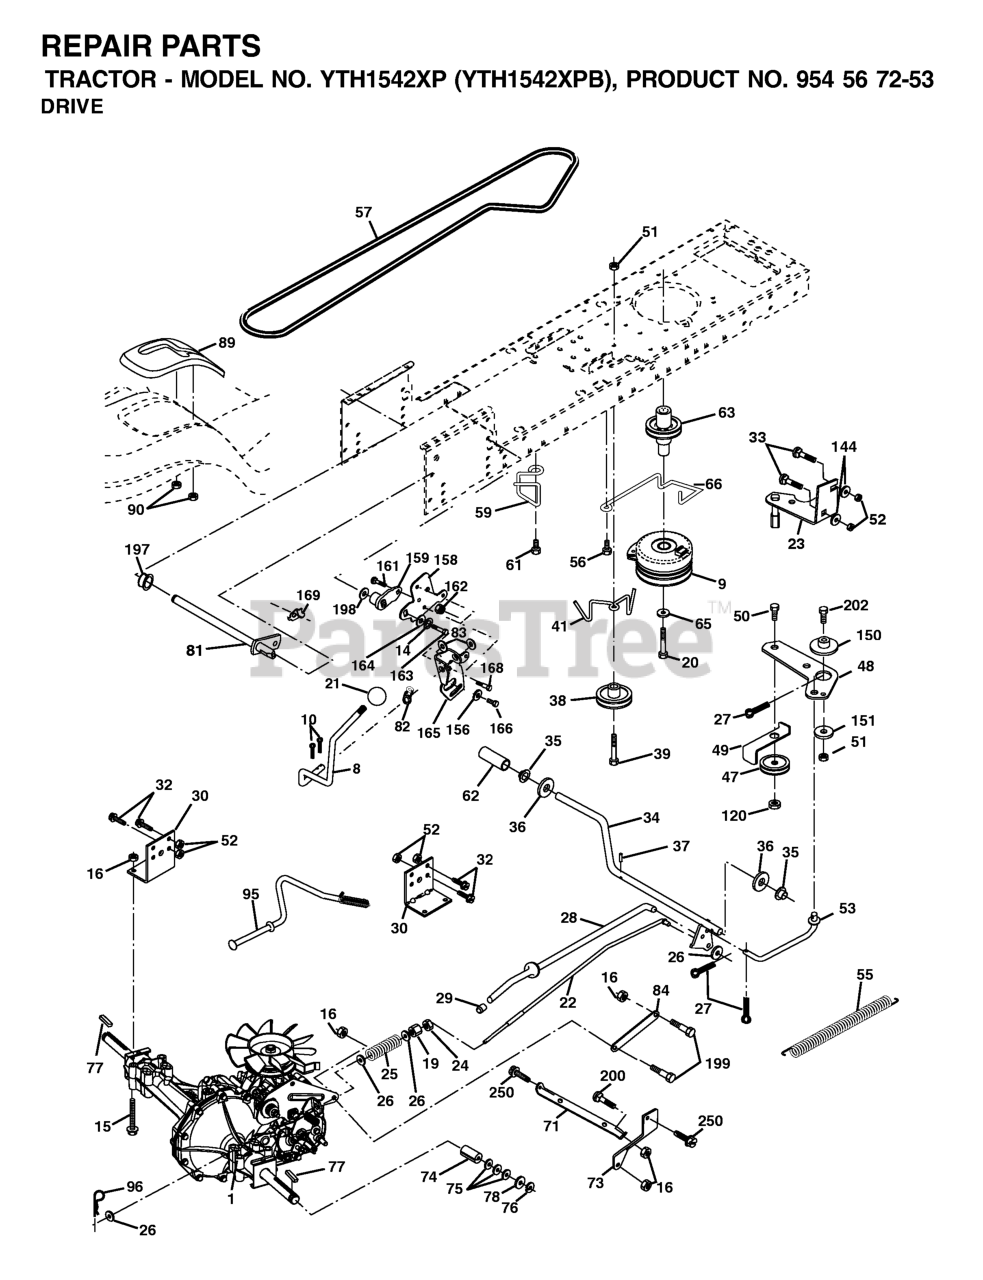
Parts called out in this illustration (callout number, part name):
8	ROD SHIFT FENDER ADJUST STLT
9	ELECTRIC CLUTCH
10	PIN COTTER
14	LOCKWASHER
15	BOLT HEX 5/16-18 GR 5
16	NUT.71038.31-18.HEX.NYLOCK
19	NUT
20	BOLT HEX
21	KNOB.DELUXE.(PISTOL.GRIP).BLAC
22	ROD BRAKE HYDRO
24	NUT
25	SPRING ROD LT
26	WASHER
27	COTTER PIN
28	ROD, PARKING BRAKE
29	PLUNGER CAP
30	BRKT, TRNSXLE MNT 20"
32	BOLT
33	RP BOLT 5/16-18 X3/4 ZN/YEL GR
34	SHAFT, FOOT PEDAL
35	BEARING.NYLON
36	WASHER LT
37	DRIVE PIN
38	PULLEY IDLER COMPOSITE
39	BOLT
41	KEEPER, BELT IDLER
47	IDLER PULLEY
48	BELLCRANK, CLUTCH
49	RETAIN BELT
50	BOLT
52	LOCKNUT
53	LINK, CLUTCH LT
55	SPRING, RETURN LT
56	SCREW.3/8-16
57	DRIVE BELT, LTH & YTH TRACTORS
59	KEEPER, BELT CENTER
61	SCREW 3/8-16X.875
62	PEDAL COVER T
63	PULLEY, ENGINE
65	LOCKWASHER
66	KEEPER BELT ENGINE
71	STRAP TORQUE LH HYDRO
73	STRAP TORQUE RH HYDRO
74	SPACER AXLE
77	SQUARE KEY
81	SHAFT ASM CROSS TAPERED
82	SHIFT SPRING
83	WASHER
84	LINK TRANSAXLE
89	SHIFT CONSOLE
90	NUT.PUSH.3/16
95	CONTROL ASM. BYPASS HYDRO
96	RETAINER M
120	NUT LOCK FLG 3/8-16 UNC
144	Washer 11/32 x 5/8 x 16 Ga SD
150	SPACER, RETAINER
151	WASHER 12/32X2X10GA
156	WASHER.SRRTD.5/16
158	BRACKET
159	HUB
161	BOLT
162	NUT.CROWNLOCK.1/4
163	BOLT
164	Washer 5/8 x .281 x 10 Ga.
165	RP BRACKET
168	BOLT.SHOULDER.5/16-18X
169	PLATE.FASTENING.CROSS.SHAFT
197	NYLINER SNAP 5/8" ID
198	WASHER.NYL.7/8IDX.105"HYD CR
199	BOLT SHOULDER 5/16-18 UNC
200	BOLT
250	SCREW 3/8-16X3/4
